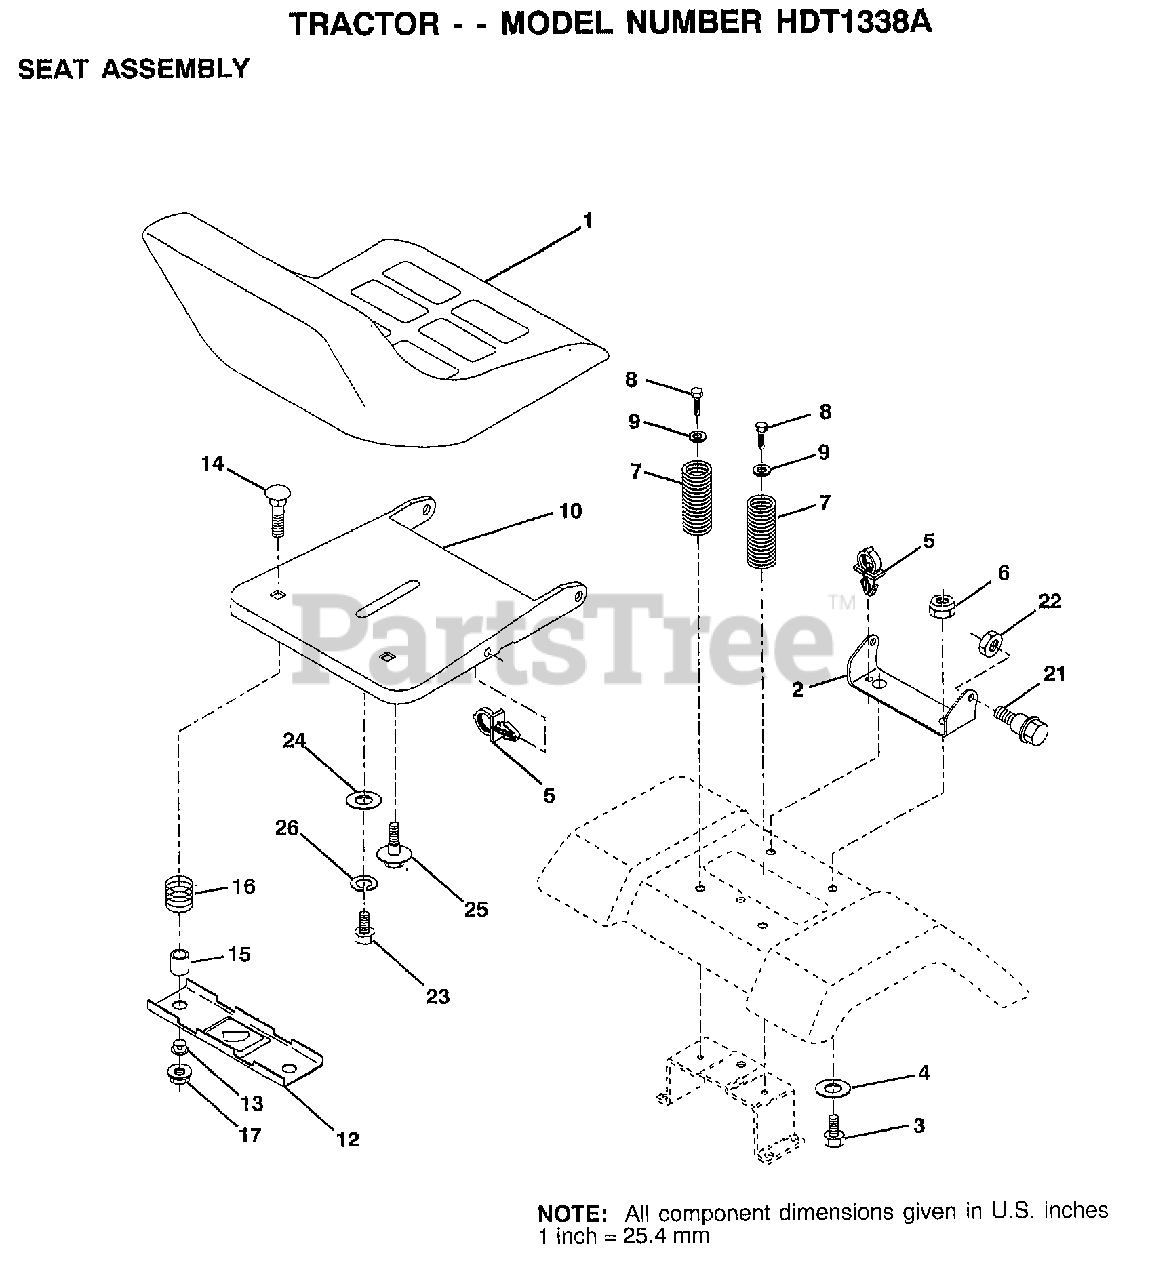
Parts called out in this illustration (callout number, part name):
2	BRACKET PVT SEAT
3	BOLT
4	WASHER PM
5	CLIP.PUSH-IN.HING
6	NUT
7	SPRING COMPRESSIO
8	SCREW
9	WASHER
10	PAN-SEAT
12	BRKT SWITCH
13	BUSHING
14	BOLT-RD HD SQ NK
15	SPLIT SPACER
16	SPRING
21	"BOLT,SHOULDER"
22	NUT
23	BOLT
24	WASHER
25	"BOLT,SHOULDER"
26	LOCKWASHER
